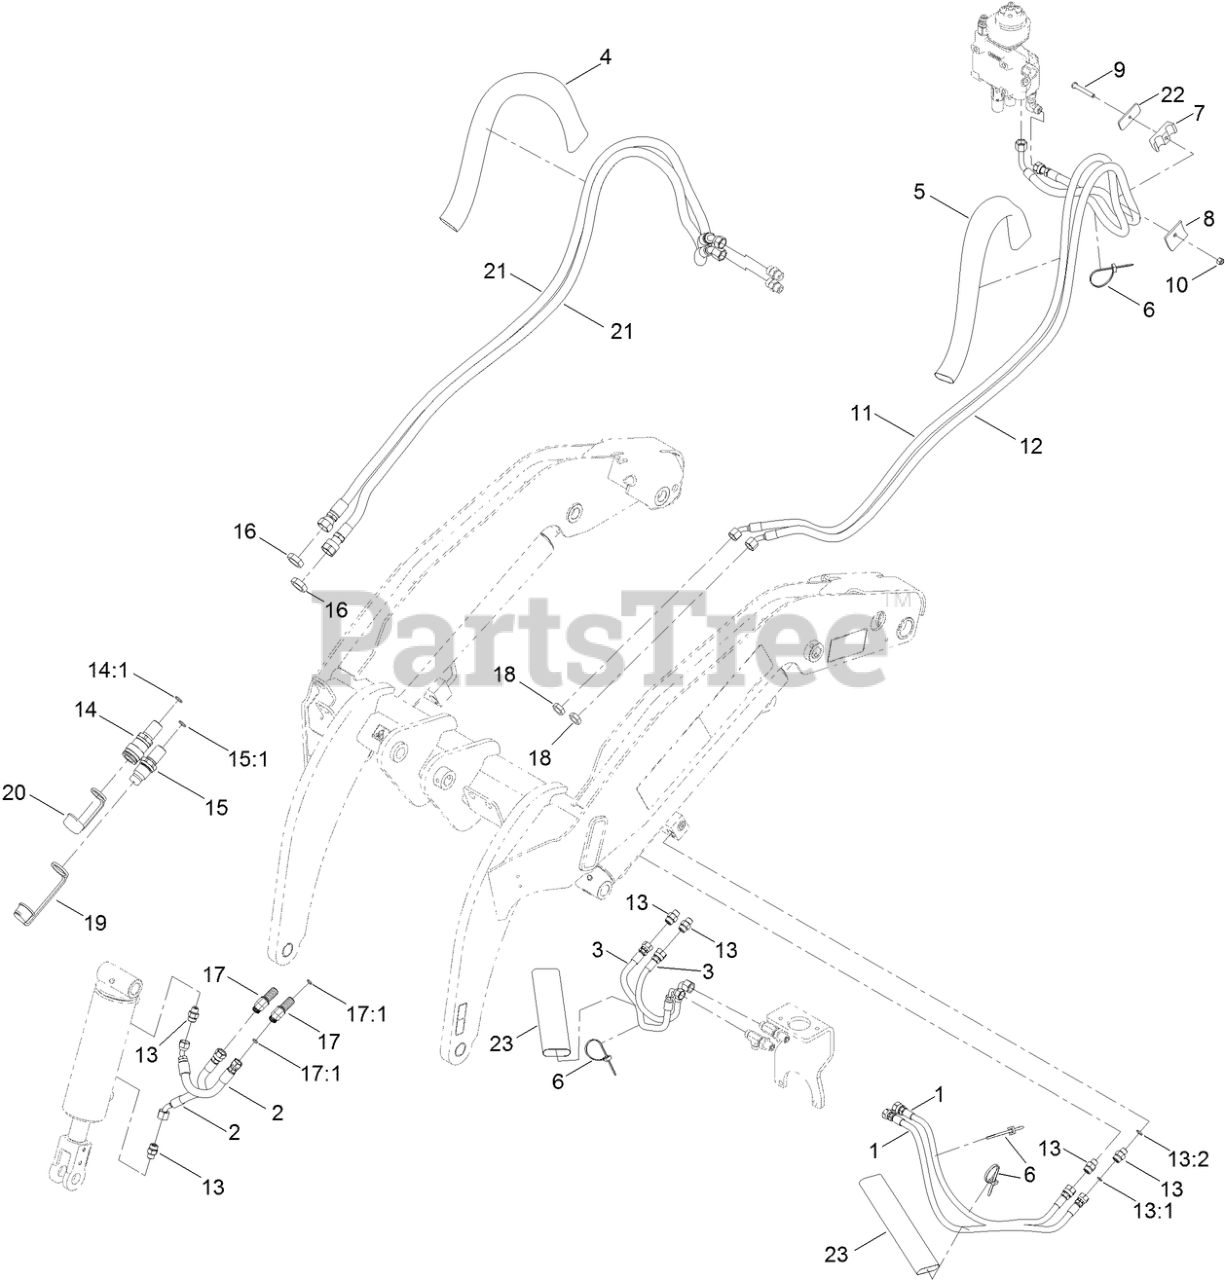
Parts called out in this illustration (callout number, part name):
1	HYD HOSE ASM
2	HYD HOSE ASM
3	HYD HOSE ASM
4	SLEEVE-PROTECTIVE
5	SLEEVE-PROTECTIVE
6	TIE-CABLE
7	CLAMP-TUBE
8	PLATE-HOLDDOWN, HOSE
9	BOLT-TAP, HH
10	NUT-LOCK, NI
11	HYD HOSE ASM
12	HYD HOSE ASM
13	FITTING-STRAIGHT
13:1	O-RING
13:2	O-RING
14	BULKHEAD COUPLER ASM
14:1	O-RING
15	BULKHEAD NIPPLE ASM
15:1	O-RING
16	NUT-LOCK, BULKHEAD
17	ELBOW-BULKHEAD, 45 DEG
17:1	O-RING
18	NUT-LOCK
19	CAP-DUST, NIPPLE
20	CAP-DUST, COUPLER
21	HYD HOSE ASM
22	PLATE-CLAMP, HOSE
23	SLEEVE-PROTECTIVE
